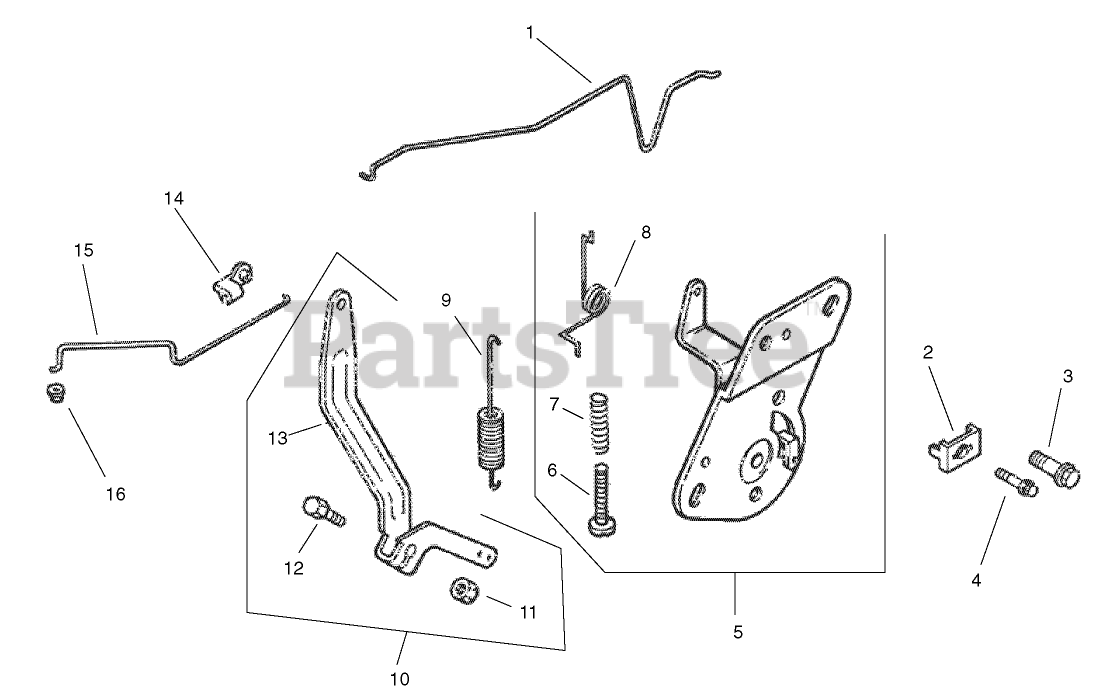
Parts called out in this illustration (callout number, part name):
1	Linkage-Choke
2	CLAMP-CABLE
3	SCREW-FLANGE, THREAD FORMING (M5X0.8X16)
4	Screw-Socket, 6 Lobed (Thread Forming, M6x1.0x20)
5	Control, speed assembly (Includes 6-8)
6	Screw-SPH,M4x0.7x25
7	Spring-Control, Speed
8	Spring-Return, Choke
9	Spring-Governor
10	Kit, Governor Lever (Incl 10-12)
11	Nut-Flange, Hex (1/4-20)
12	Bolt-Square Neck, Round Head (1/4-20x1)
13	Lever-Governor
14	BUSHING-RETAINING, LINKAGE
15	Linkage-Throttle
16	BUSHING-LINKAGE, THROTTLE
